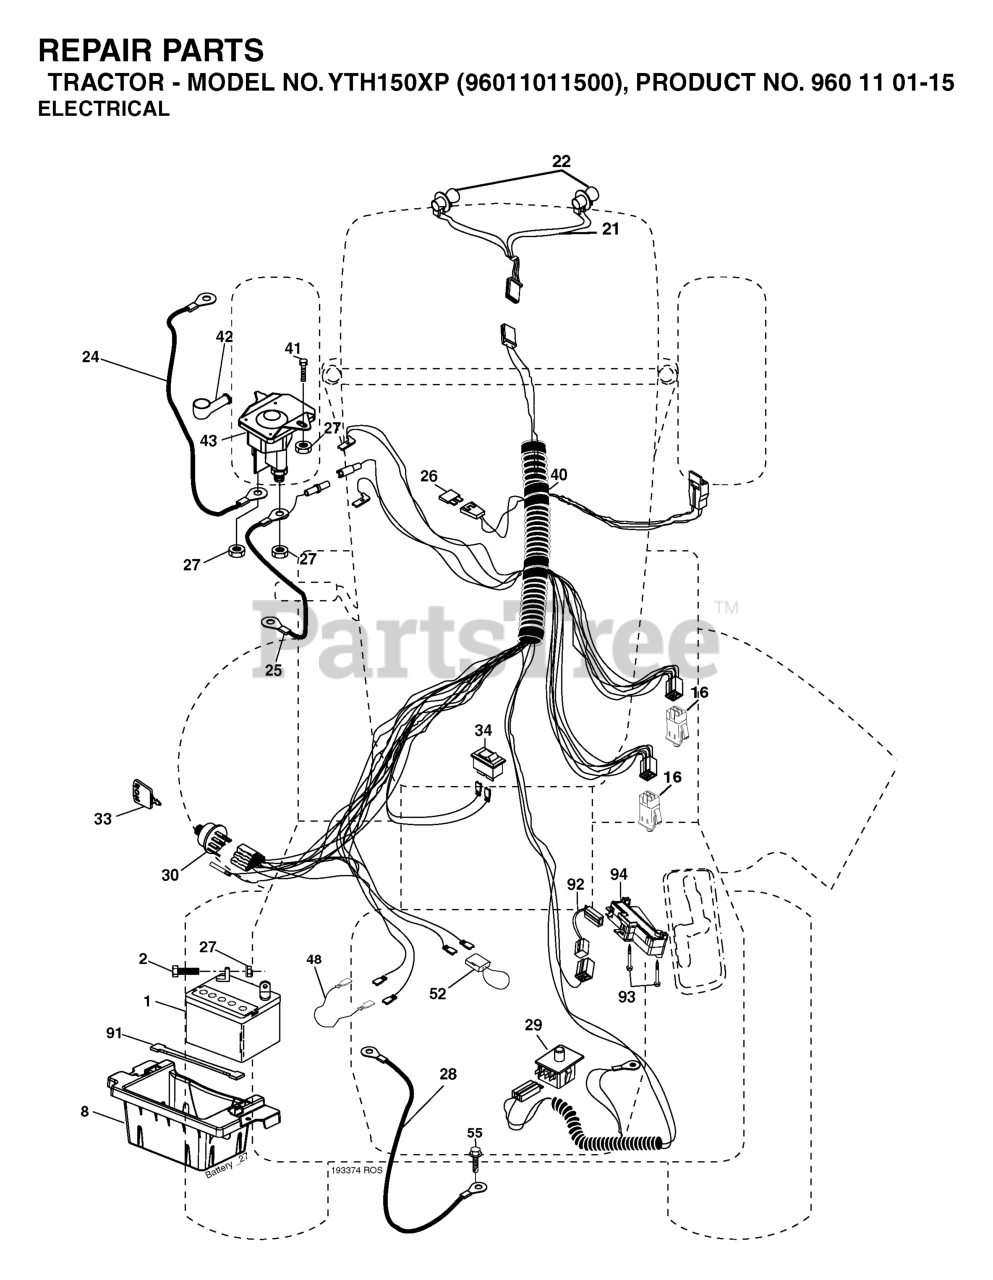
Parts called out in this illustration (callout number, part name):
1	BATTERY 12V .35 AMP
2	BOLT.HEX.1/4.X.3/4.DICHROMATE
8	BOX.BATTERY.MOUNT.FRONT.LT
16	SWITCH INTERLOOK PUSH-IN
21	HARNESS.W/LIGHT SOCKET
24	BATTERY CABLE GT
25	CABLE BATTERY 6 GA 22" W/16W
26	FUSE 20AMP
27	NUT
28	CABLE GROUND 6 GA 21" 90T BLK
29	SWITCH.SEAT.DP W/RAMPS
30	SWITCH.IGN.DELTA.W.LGH.ROS
33	KEY MLD GEN DELTA
41	BOLT
42	TERMINAL COVER
43	SOLENOID.W/BRASS.PLUNGER
48	ADAPTER.AMMETER
52	WIRE PROTECTION LOOP
55	Screw 5/16-18 x 1/2 Hex, Self Tapping 5/16-18 x 1/2
90	COVER TERMINAL
91	STRAP.BATTERY.MOUNT.FRONT(2 2)
92	HARNESS.PIGTAIL.REVERSE.SWITCH
93	SCREW.PLASTITE
94	MODULE.REVERSE.ROS
